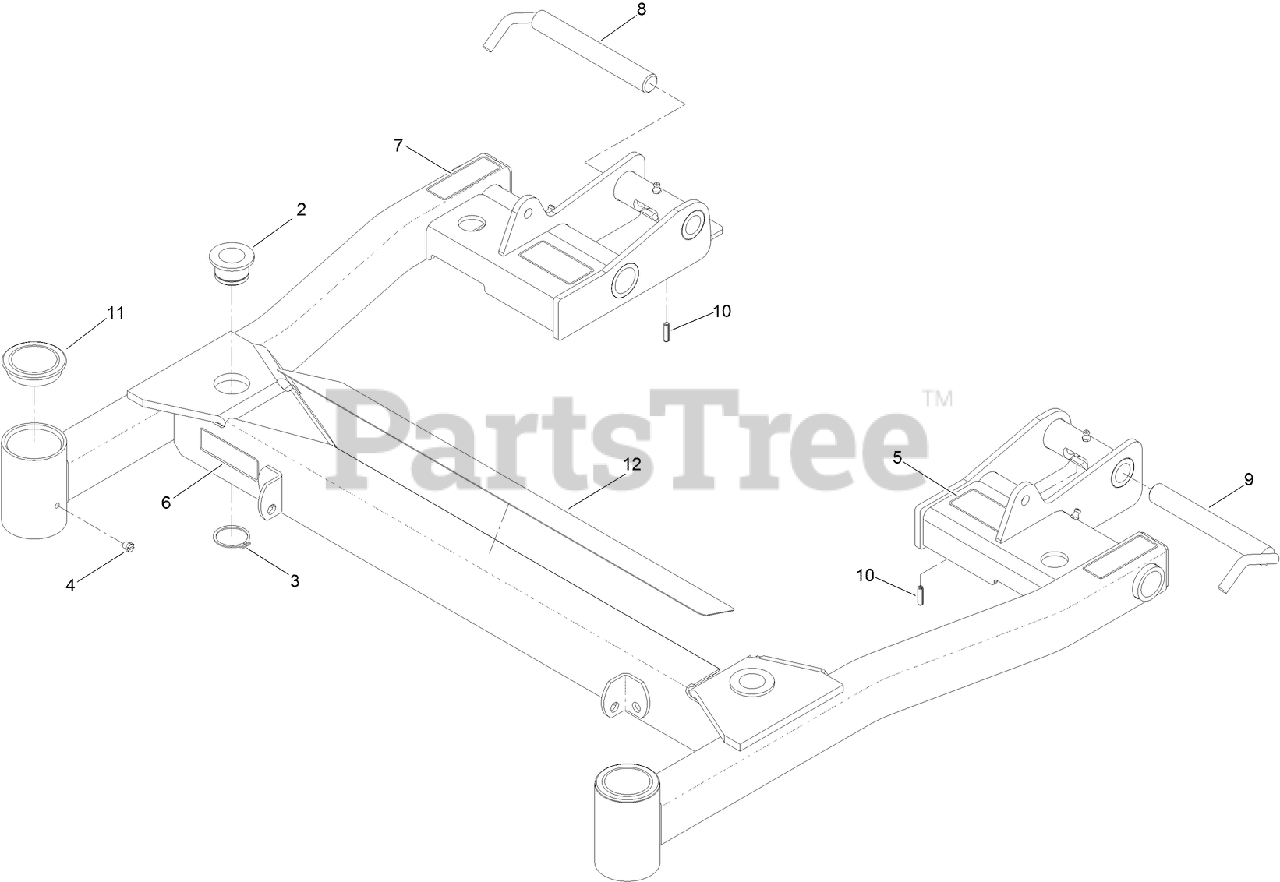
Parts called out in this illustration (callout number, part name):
2	BUSHING-SUPPORT, DECK
3	RING-RETAINING
5	DECAL-SPRING
6	DECAL-DANGER
7	DECAL-FOLDING DECK
8	LOCK-DECK, RH
9	LOCK-DECK, LH
10	PIN-SPRING
11	CAP-GREASE
12	PAD-ANTI SKID
